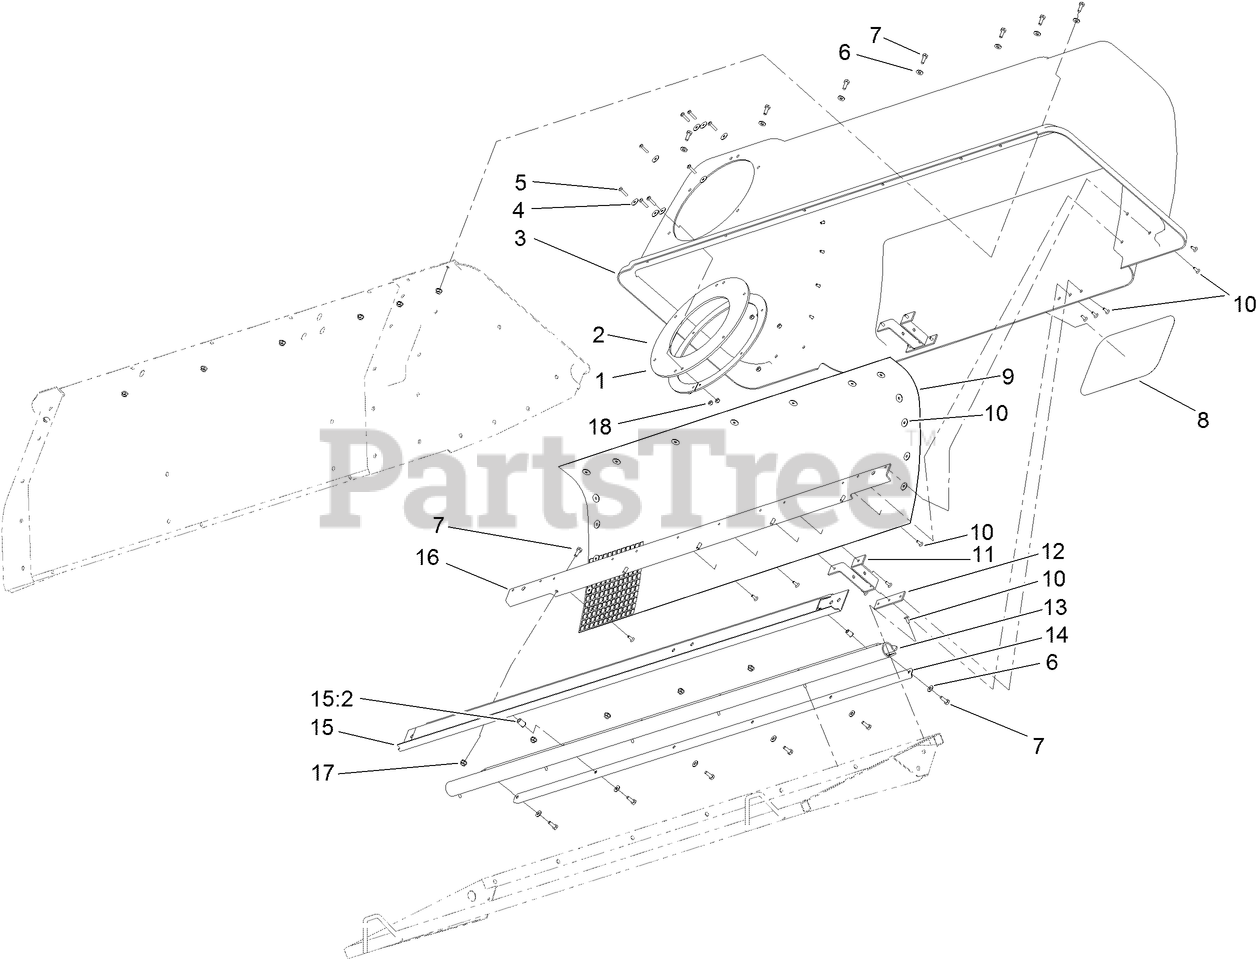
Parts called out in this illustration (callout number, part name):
1	CLAMP-SEAL
2	SEAL-TUBE
3	HOOD ASM
4	WASHER-FLAT
5	SCREW-PPH
6	WASHER-FLAT
7	SCREW-HH
8	DECAL
9	Screen-Bagger
10	RIVET-BLIND
11	Bracket-Mount
12	Plate-Latch, Reinforcement
13	SEAL-DOOR HINGE
14	STRAP-HOLD DOWN
15	REAR CROSSMEMBER ASM
15:2	INSERT-NUT
16	SUPPORT-SCREEN
17	NUT-HF
18	NUT-LOCK, NI
